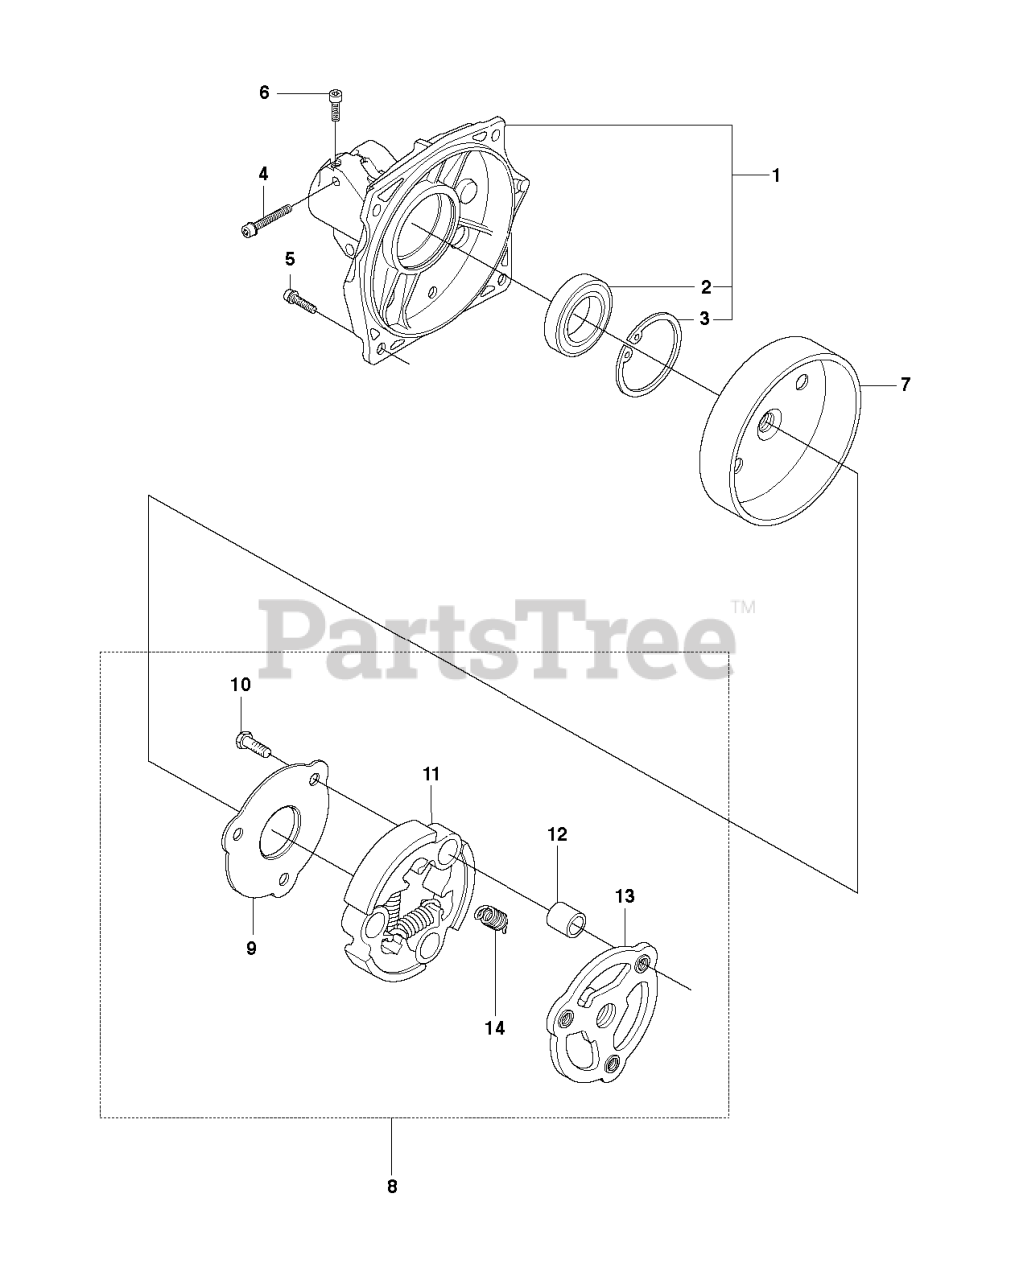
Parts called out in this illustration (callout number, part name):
1	CLUTCH COVER
2	BALL BEARING 6202-2RS1
3	RETAINING RING SGH 35
6	SCREW MC6LS 5X12
7	CLUTCH DRUM ASSM.
8	CLUTCH CPL
10	SCREW
14	CLUTCH SPRING
